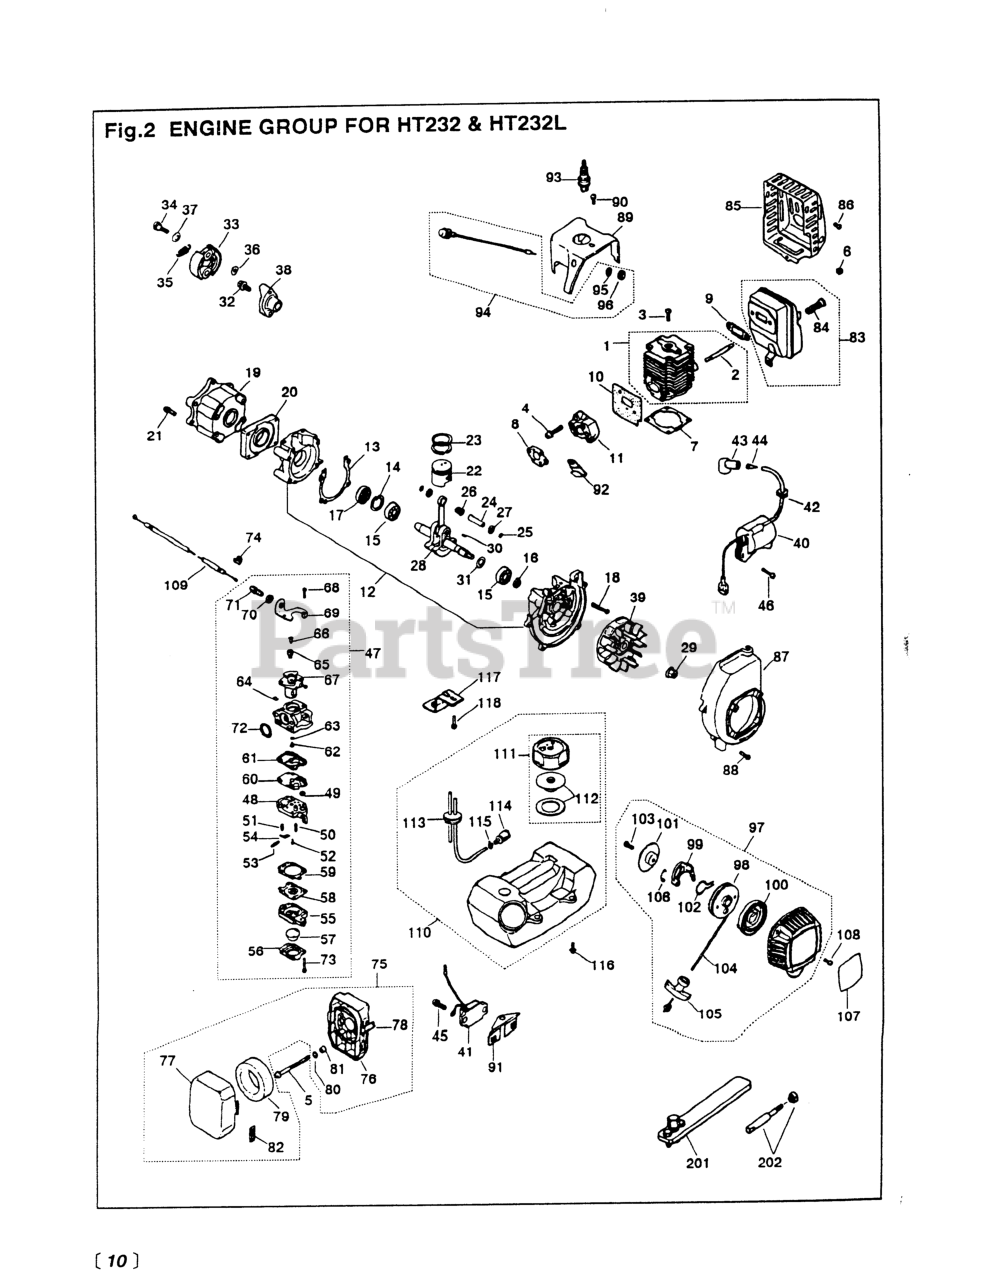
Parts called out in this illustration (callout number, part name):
1	CYLINDER-C
2	STUD
3	SCREW, M5 X 16
5	SCREW, M5 X 55
6	NUT
11	INSULATOR
12	CRANKCASE
14	RING, SNAP, M28 x 1.2
15	BEARING
16	SEAL, OIL
17	SEAL, OIL (RPLS 1140-21220)
18	SCREW, M5 x 30(RPLS 0263-00530
19	CASE, CLUTCH
22	PISTON (USE 5600-41111)
23	RING, PISTON (RPLS 1850-41210)
24	PIN, PISTON 5x8x26
25	RING, SNAP (RPLS 1101-41320)
27	WASHER
28	CRANKSHAFT
30	KEY
32	BOLT, M6 x 14(RPLS 0224-00614)
34	BOLT
36	WASHER, FLAT (USE 182303)
37	WASHER (RPLS -51241)
38	PLATE, CLUTCH
41	UNIT
44	SPRING
45	SCREW, M5 X 12
46	SCREW, M4 x 20
47	CARBURETOR (NLA)
48	BODY, PUMP
50	VALVE, INLET
52	SCREW, METERING LEVER PIN
53	PIN, METERING LEVER
54	LEVER
55	BODY, PURGE
56	JET
57	PUMP, PRIMING
58	DIAPHRAGM (USE 4810-81260)
59	GASKET, DIAPHRAGM
60	DIAPHRAGM
61	GASKET, PUMP
62	JET
63	RING, O
64	RING
65	SWIVEL
67	VALVE ASSEMBLY
68	SCREW
69	BRACKET
70	NUT, CABLE ADJUSTER
71	SCREW, CABLE ADJUSTER
72	RING, PACKING
73	SCREW
74	CAP, CABLE END
75	CLEANER ASSEMBLY
76	BODY
77	COVER
81	SLEEVE (USE 1918-82170)
82	LABEL
83	MUFFLER ASSEMBLY
84	ARRESTER (RPLS 5850-15140)
87	COVER (REPLACES -31101)
88	SCREW, M4 x 14
89	COVER, CYLINDER
91	BRACKET (RPLS -72240)
92	CLAMP
94	SWITCH ASSY (RPLS -72200)
95	WASHER
96	NUT
97	STARTER ASSEMBLY
99	RATCHET
101	PLATE (NLA) (RPLS -75240)
102	SPRING, FRICTION
103	SCREW (USE -75261)
105	KNOB
106	SPRING
108	SCREW, M4 X 12
112	VALVE COMPLETE
113	PIPE ASSEMBLY
114	5500-85400 (RRLS. 1750-85300)
115	CLIP (REPLACES 2841-31280)
117	BRACKET-NO LONGER AVAILABLE
